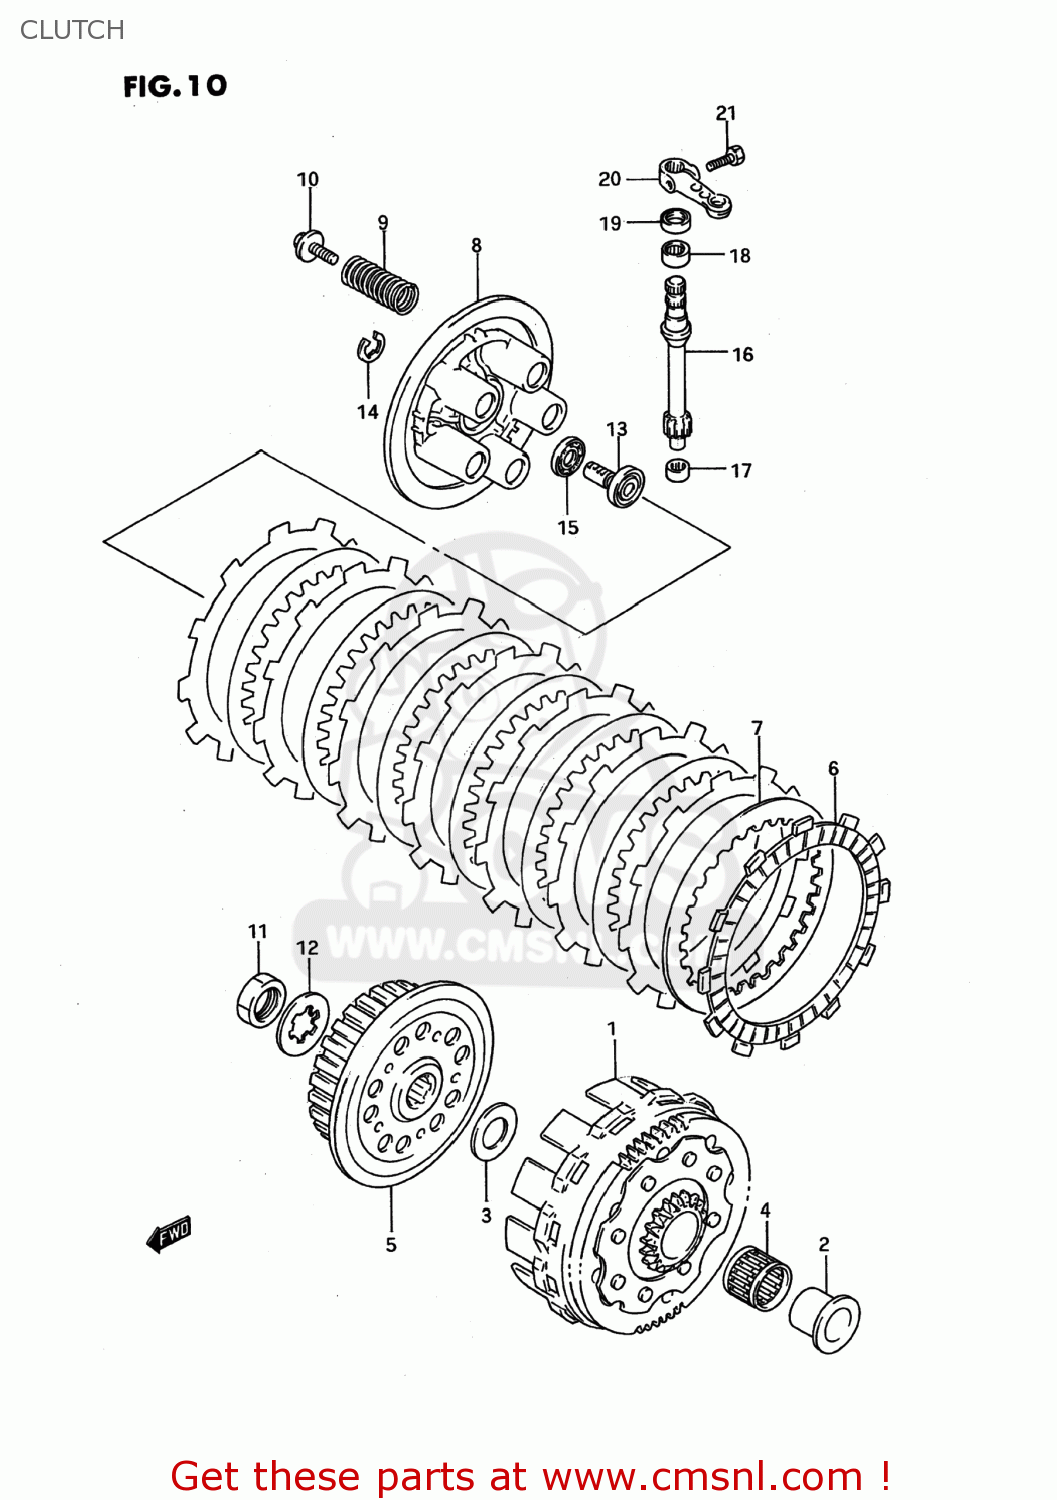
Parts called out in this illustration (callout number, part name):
1	GEAR ASSEMBLY,PRIMARY DRIVE
2	SPACER,PRIMARY DRIVEN
3	WASHER
4	BEARING(25X30X22)
5	HUB,CLUTCH SLEEVE
6	PLATE,CLUTCH DRIVE(T:2.8) (NAS)
7	PLATE,CLUTCH DRIVEN(T:1.4) (NAS)
8	DISC,CLUTCH PRESSURE
9	SPRING
10	BOLT(5X25)
11	NUT (20MM)
12	WASHER,LOCK
13	RACK,CLUTCH RELEASE
14	E RING
14A	CIRCLIP,10MM
15	BEARING(10X22X2.8)
16	PINION,CLUTCH RELEASE(NT:12)
17	BEARING(9X13X10)
18	BEARING(12X16X10)
19	SEAL,OIL(10X17X5)
20	ARM,CLUTCH RELEASE
21	BOLT
